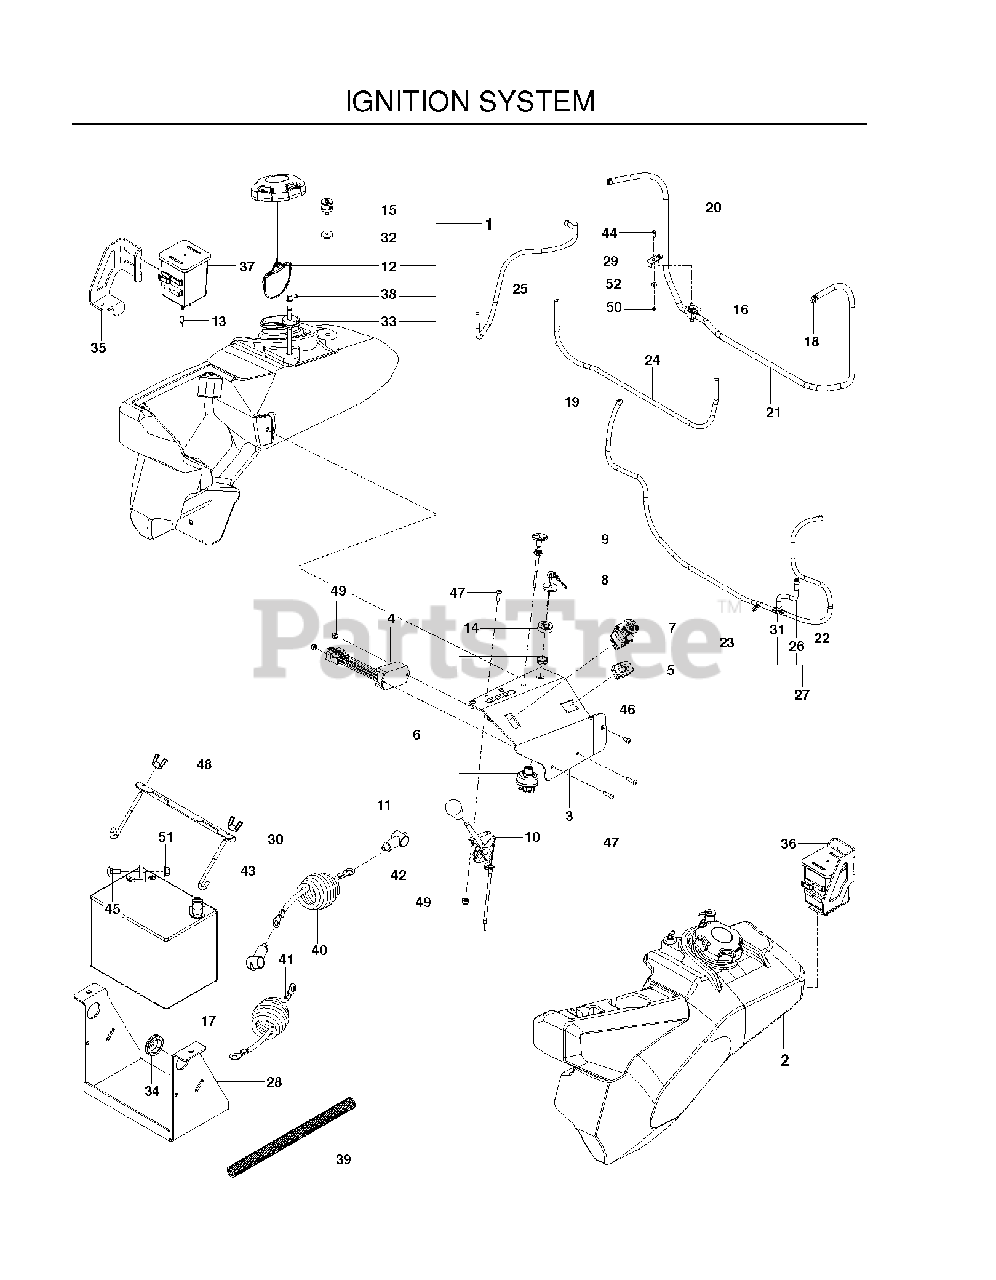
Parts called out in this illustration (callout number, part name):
4	TIMER, SEAT
5	HOUR METER
6	SWITCH, IGNITION, INDAK
7	SWITCH, PTO 10 AMP
8	KEY, IGNITION
9	CABLE, CHOKE, 48"
10	CABLE, THROTTLE, 46"
11	KNOB - SHIFT
12	CAP, FUEL
15	VALVE, FUEL CHECK
16	FUEL VALVE
17	BATTERY, 12 V 330 AMP
18	HOSE CLAMP
19	CLAMP, HOSE
22	HOSE, 3/16" VAPOR, 21"
23	HOSE, VAPOR 3/16 X 39"
24	HOSE, VAPOR 3/16 X 30"
25	FUEL LINE 33"
28	BRACKET, BATTERY, BLK
29	BRACKET, VALVE, BLACK
30	BRACKET, BATTERY MOUNT
32	GROMMET, CHECK VALVE
33	RUBBER GROMMET
34	RUBBER GROMMET
37	CANNISTER, CARBON
39	LOOM, SPLIT, CONVOLUTED
40	CABLE, POSITIVE, 55"
41	CABLE, NEG, 55"
42	INSULATOR
43	HOOK, "J"
44	HCS 1/4C X 3/4 HCS
45	BOLT 5/16C X 3/4" CARRIAGE
46	SCR #10-24 X 3/8 SKT HD BLK OX
47	SCR #10-24 X .75 SKT HD BLK
48	WING NUT 1/4
49	NUT 10-24 NYLOC
50	JAM NUT 1/4C
51	5/16-18 NYLOC FLANGE NUT
52	WASHER 1/4 FLAT
